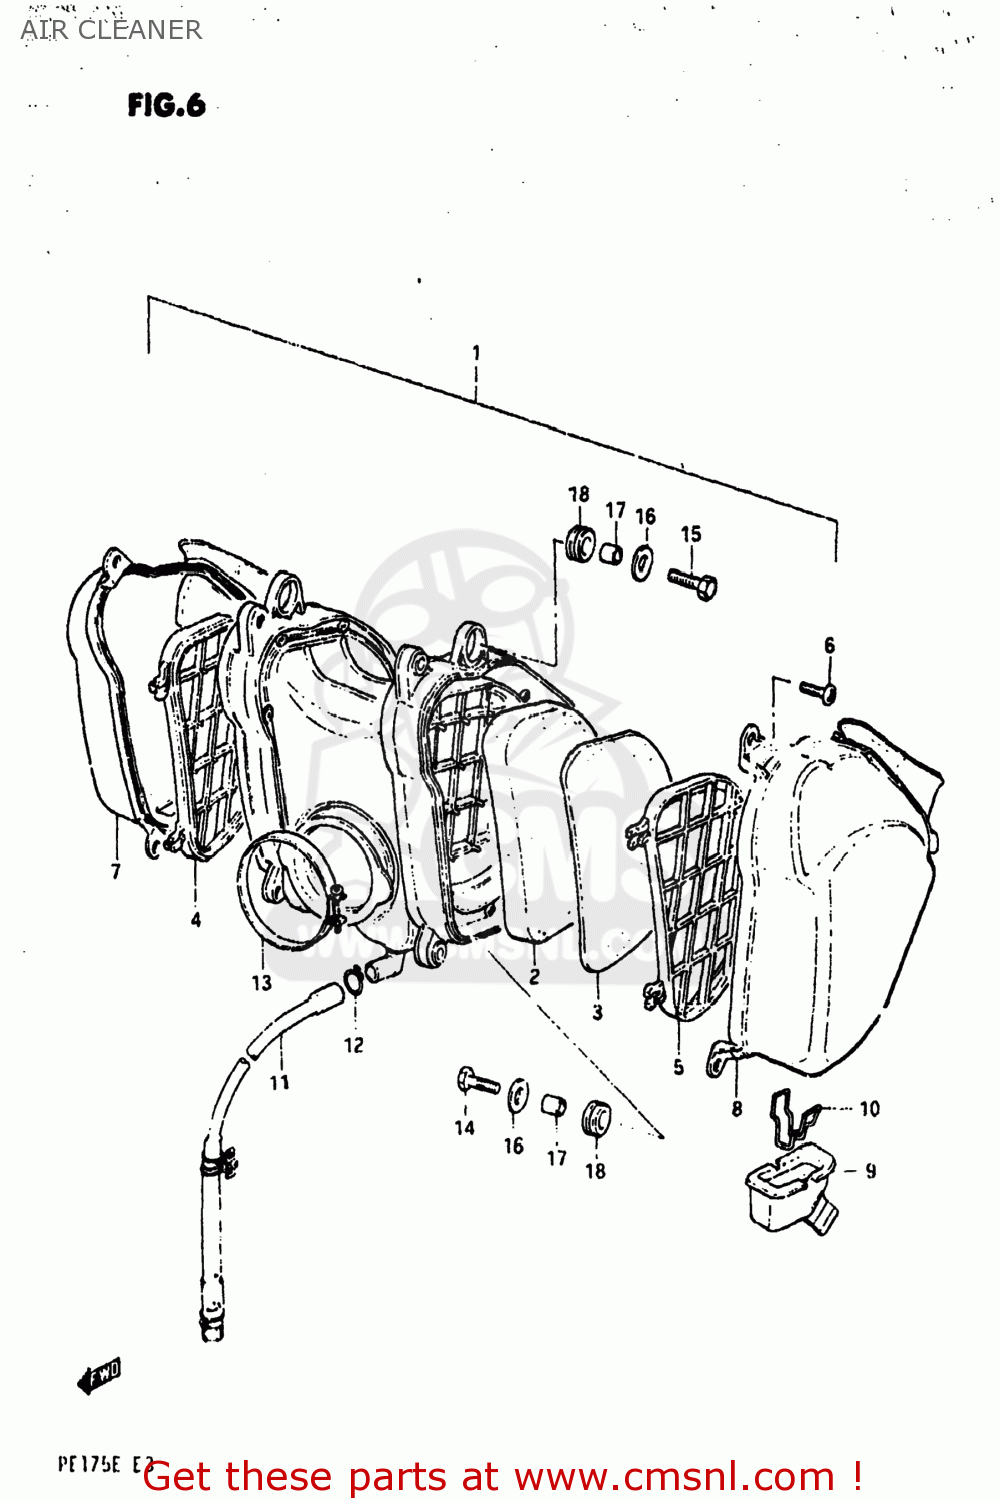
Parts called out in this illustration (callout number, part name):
1	CLEANER ASSEMBLY,AIR
2	FILTER
3	FILTER,2ND
4	HOLDER,AIR CLEANER,RIGHT
5	HOLDER,AIR CLEANER,LEFT
6	SCREW
7	CAP,AIR CLEANER,RIGHT
8	CAP,AIR CLEANER,LEFT
9	DRAIN,AIR CLEANER
10	DRAIN STOPPER
11	DRAIN TUBE
12	CLIP
13	CLAMP
14	BOLT
15	BOLT, UPPER
16	WASHER
17	SPACER (7X9X7)
18	CUSHION
